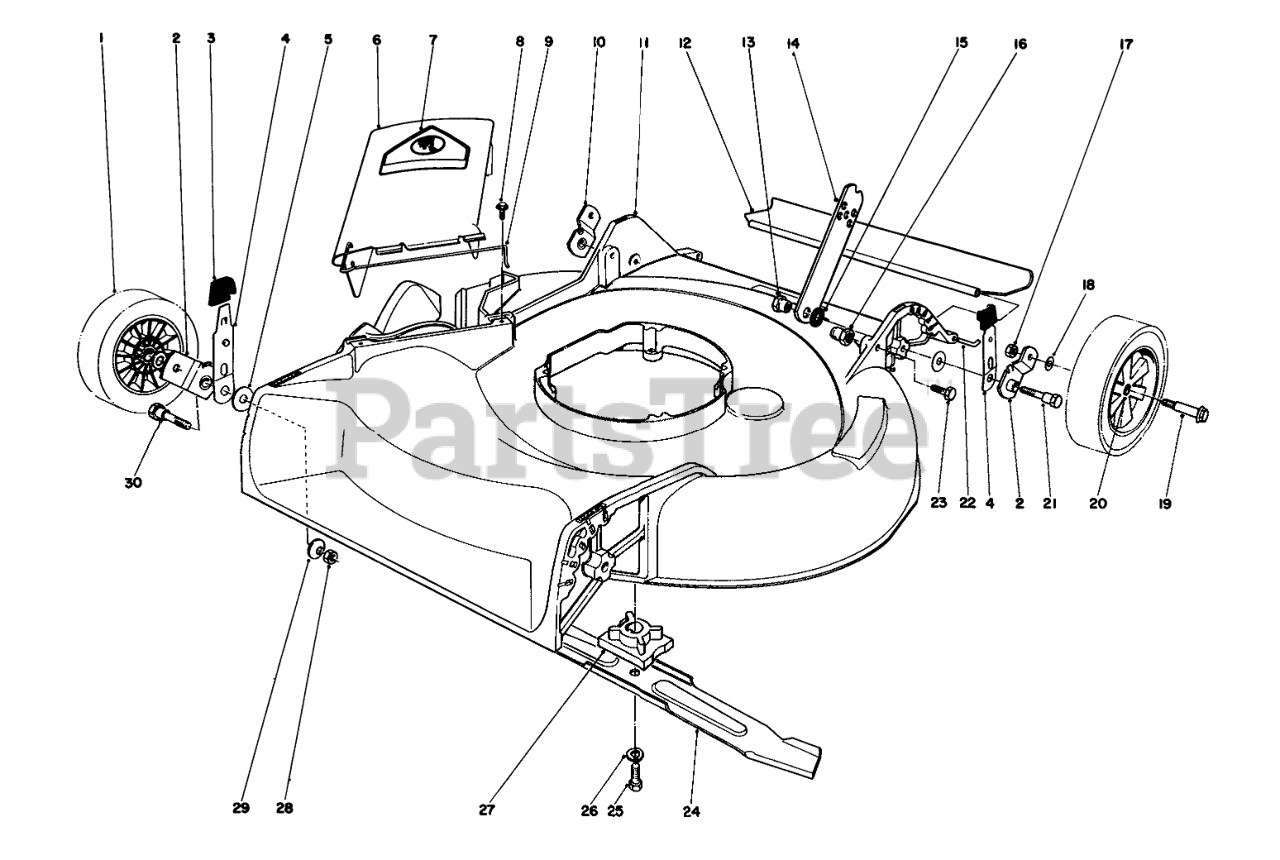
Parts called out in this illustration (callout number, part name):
1	Wheel & Tire Assembly (Incl. Ref. #20)
2	Pivot Arm
3	KNOB-ARM
4	SPRING ARM ASM
5	WASHER-PIVOT
6	Deflector Assembly (Incl. Ref. #7 & 9)
7	DECAL-DANGER
8	SCREW-HWH
9	SPRING HINGE
10	Pivot Arm
11	HOUSING/DECAL
12	REAR SAFETY SHIELD 21
13	HANDLE PIVOT NUT
14	HANDLE LATCH
15	SPACER
16	HANDLE PIVOT NUT
17	NUT-LOCK
18	WASHER
19	WHEEL BOLT
20	BUSHING
21	PIVOT SCREW
22	SHIELD ROD
23	SCREW-HH
24	Blade
25	SCREW-HH
26	WASHER-LOCK
27	BLADE RETAINER
28	NUT-LOCK, NI
29	WASHER-BELLEVILLE
30	PIVOT SCREW
